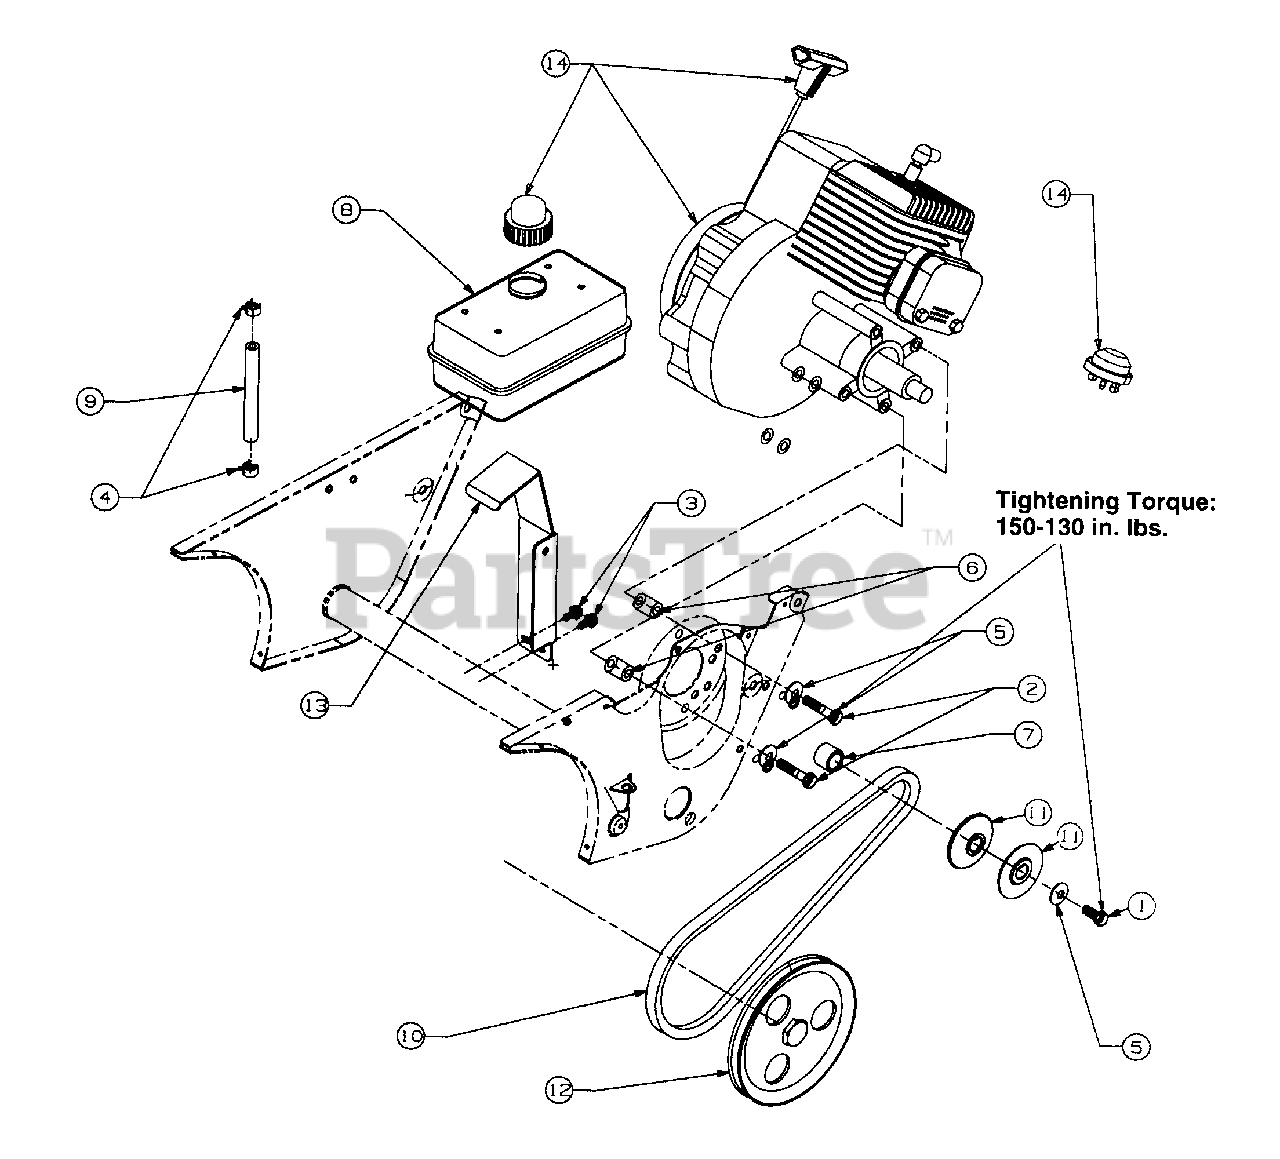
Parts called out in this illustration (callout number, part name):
1	Screw - Hex Cap
2	Screw - Hex Cap
3	Screw - Washer
4	Clamp - Hose
5	Washer - Bell
6	Spacer
7	Spacer
8	Tank - Fuel
9	Hose - Fuel 12"
10	V-Belt
11	V-Pulley Half
